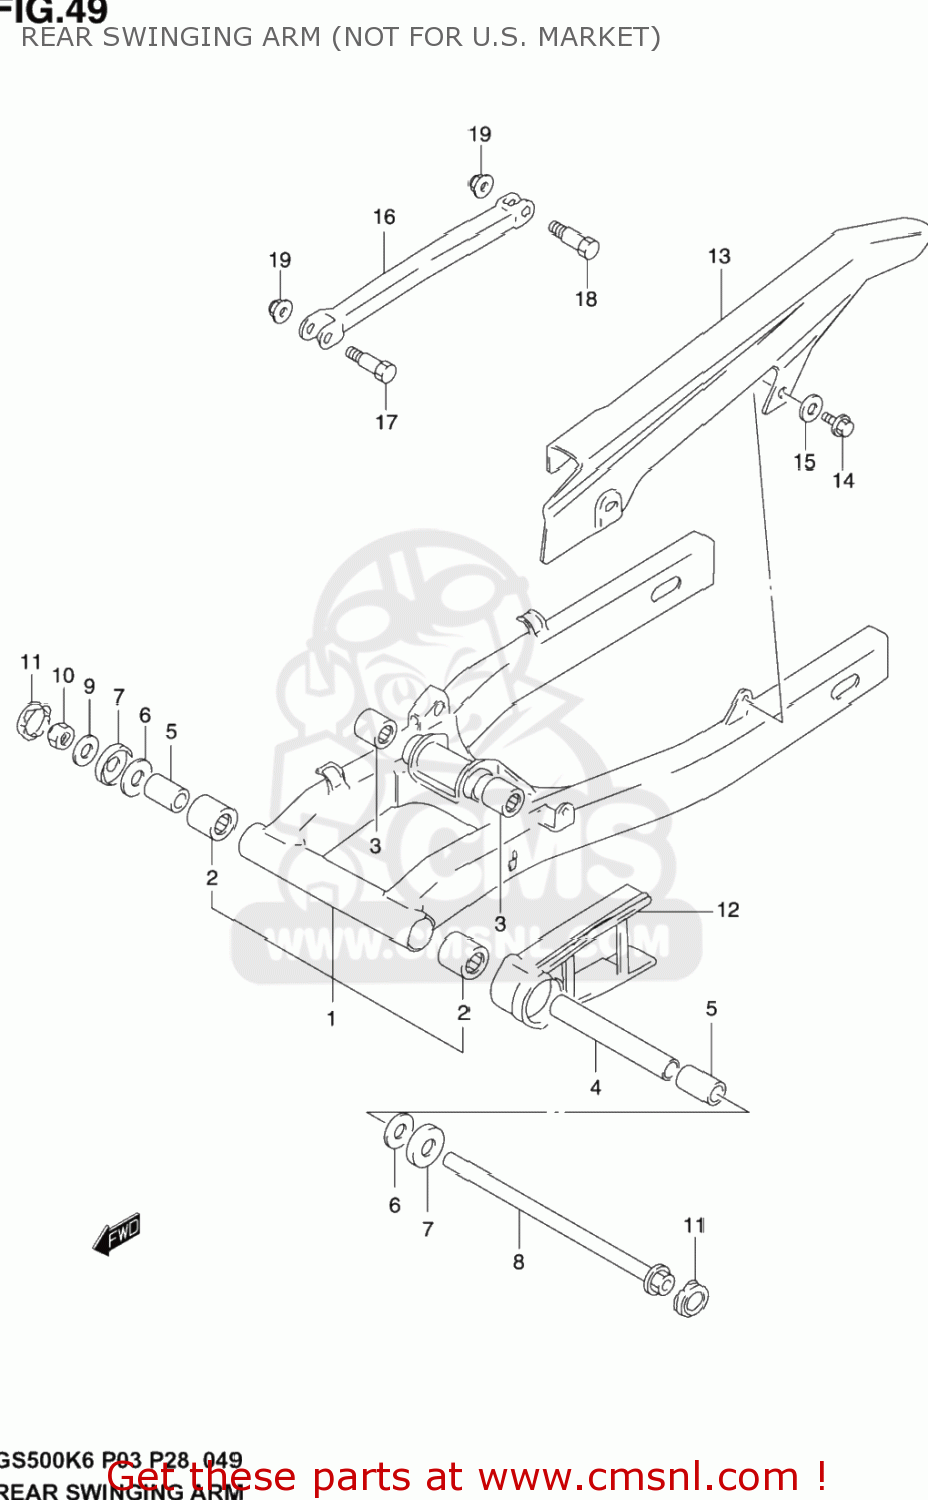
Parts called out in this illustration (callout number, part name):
1	SWINGING ARM
2	BEARING(22X29X30)
3	BEARING(17X24X25)
4	SPACER, CENTER
5	SPACER, PIVOT BEARING
6	WASHER(14.2X34X1)
7	CVR,RR SWGARM DUST SEAL(OD:40)
8	SHAFT,RR SWINGINGARM PIVOT
9	WASHER(14.5X29X2.3)
10	NUT
11	CAP,RR SWINGING ARM PIVOT
12	BUFFER,CHAIN TOUCH DEFENSE
13	CASE, CHAIN
14	SCHRIOEF
15	WASHER
16	TORQUELINK,RR
17	BOLT(10X41)
18	BOLT(10X34)
19	NUT
